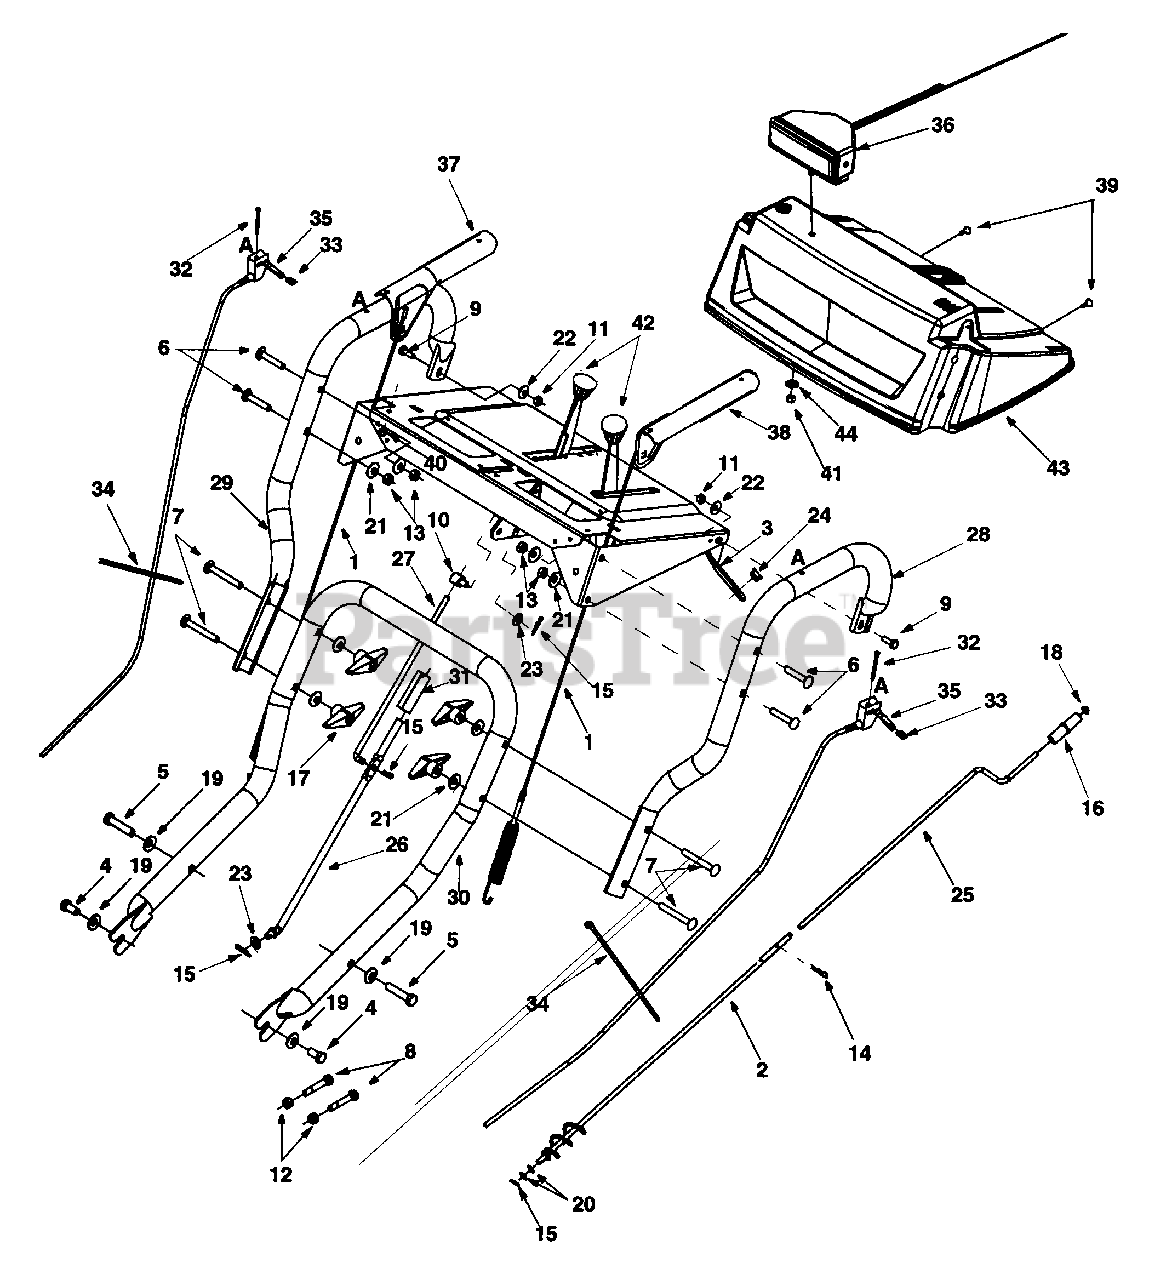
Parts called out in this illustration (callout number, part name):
1	Cable Assembly: Auger/Drive Engagement
2	Chute Crank Assembly
3	Chute Crank Bracket
4	Hex Screw 3/8-16 x .75"
5	Hex Screw 3/8-16 x 1.75"
6	Carriage Bolt 5/16-18 x 1.75"
7	Carriage Bolt 5/16-18 x 2.5"
8	Shear Bolt 5/16-18 x 1.75"
9	Hex Screw 1/4-20 x .75"
10	Ferrule
11	Hex Nut 1/4-20
12	Hex Lock Nut
13	Hex Nut
14	Hairpin Clip
15	Hairpin Clip
16	Chute Crank Knob
17	Knob
18	Push Cap
19	Bell Washer
20	Flat Washer
21	Beleville Washer
22	Bell Washer
23	Flat Washer
24	Plastic Bushing
25	Chute Crank
26	Lower Shift Rod
27	Upper Shift Rod
31	Clutch Rod Connector
32	Oval C-Sunk Screw
33	Flat Weld Nut
34	Cable Tie
35	Trigger Control
36	Light Assembly
36	Halogen Lamp
36	Lens Assembly
37	Handle Engagement RH
38	Handle Engagement LH
39	Special B Screw
40	Hex Sems Nut
41	Hex Lock Nut
42	Shift Knob
43	Handle Panel
44	5/16 Washer
